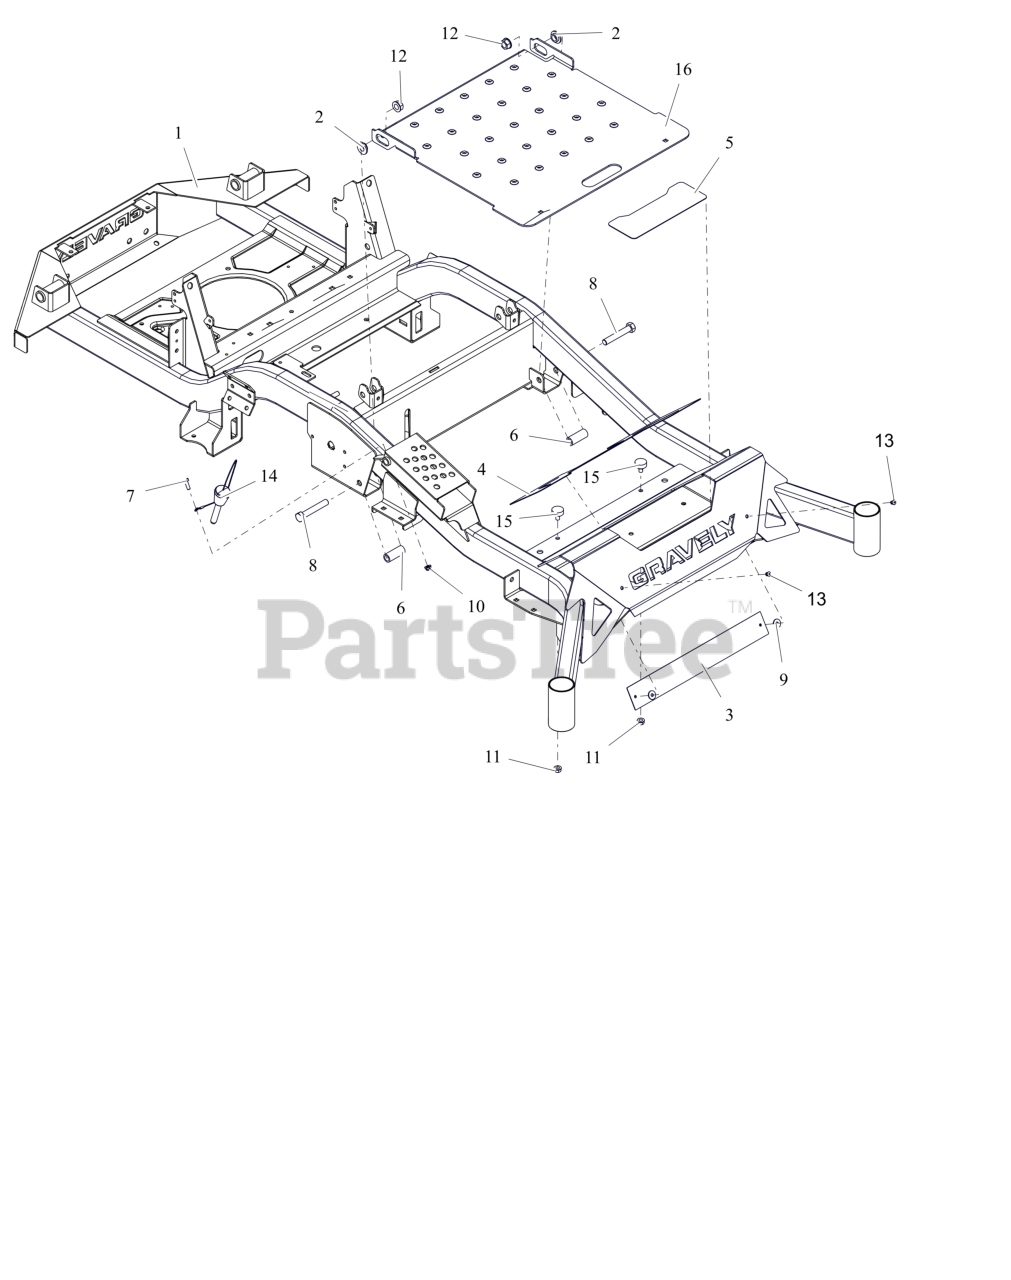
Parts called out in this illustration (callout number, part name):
1	WLDMT, MAIN FRAME -HD 60 (RED)
2	BSHG-FLG .515X.750X.310X1.120
3	PLATE, BACK FOOT-REST XL
4	GRIP, FRONT
5	GRIP, STEP
6	SPACER, .515X.75X1.83
7	BLT, HEX .25-20X.75 G5 ZCC
8	BLT, HEX .50-13X3.00 G5 ZCC
9	WSHR, RBR W/ADHESIVE .25X.75X.06
10	NUT,NYL-FLG .25-20 GF ZCC
11	NUT,SPNLK-FLG .31-18 G5 ZCC
12	NUT-LK-TOP-FLG .500-13 GF ZCC
13	RIVET, .1875 AL/AL .126-.250
14	PIN, MAGNETIC .50X2.50
15	BUMPER, RUBBER
16	KIT,ACCESS PANEL W/DECALS-RED
